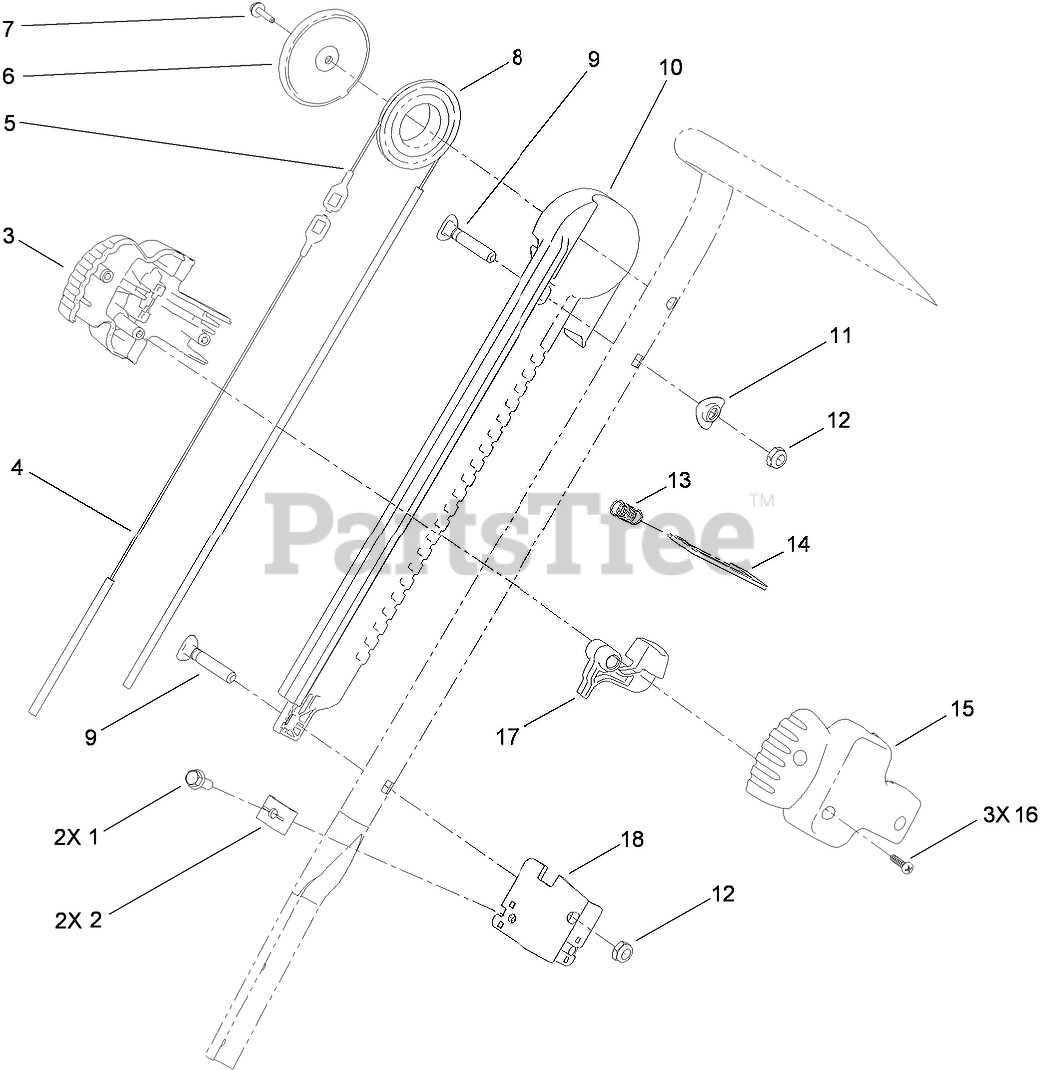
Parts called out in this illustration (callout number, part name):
1	SCREW-HWH
2	CLAMP-CABLE
3	HANDLE-SLIDER, RH
4	CABLE-CHUTE, SHORT
5	CABLE-CHUTE, LONG
6	COVER-PULLEY
7	SCREW-HWH
8	PULLEY-SLIDER
9	SCREW-HANDLE
10	TRACK-SLIDER
11	WASHER
12	NUT-LOCK, NI
13	SPRING-TRIGGER
14	PLATE-LOCK, CHUTE
15	HANDLE-SLIDER, LH
16	SCREW-PPH
17	TRIGGER
18	BRACKET-CABLE
